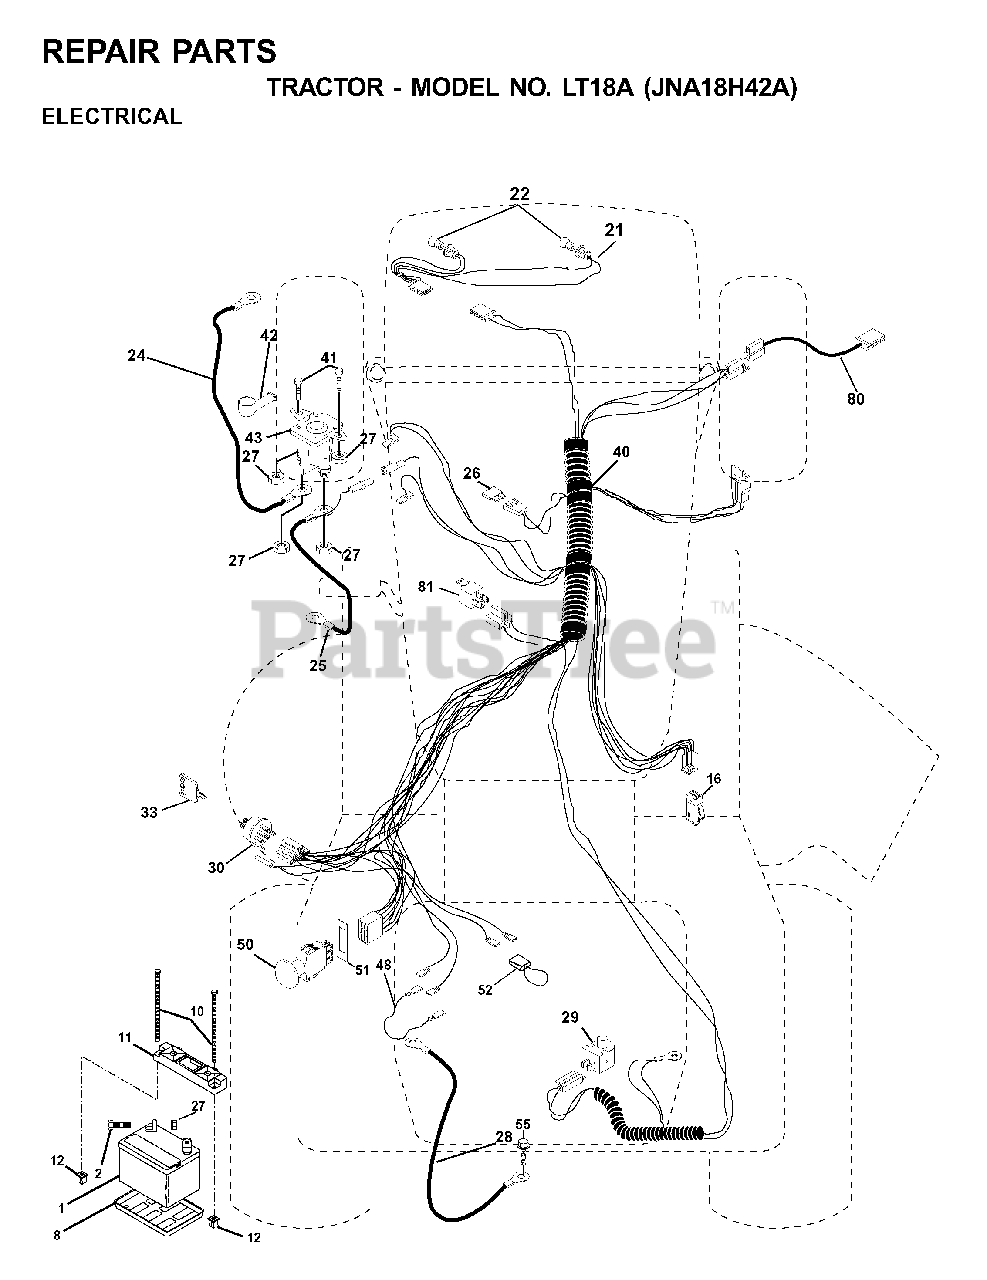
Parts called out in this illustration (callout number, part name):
1	REPL BY 532 12 38-99
8	TRAY.BATTERY
10	BOLT 1/4-20 X 7.5
11	BATTERY HOLDDOWN
12	NUT, PUSH NYLON 1/4" BATTERY
16	SWITCH INTERLOCK
22	LIGHTBULB
24	BATTERY CABLE GT
25	CABLE BATTERY 6 GA 22" W/16W
26	FUSE 20AMP
27	NUT
28	CABLE GROUND 6 GA 21" 90T BLK
29	PLUNGER SWITCH (COLOR:OLIVE)
30	IGNITION SWITCH
33	KEY MLD GEN DELTA
40	HARNESS, ELEC IGNITION
42	TERMINAL COVER
43	REPL BY 532 1461-54
50	PTO SWITCH
51	RETAINING RING
52	WIRE PROTECTION LOOP
80	HARNESS, CLUTCH
81	RELAY.ASSY.T
